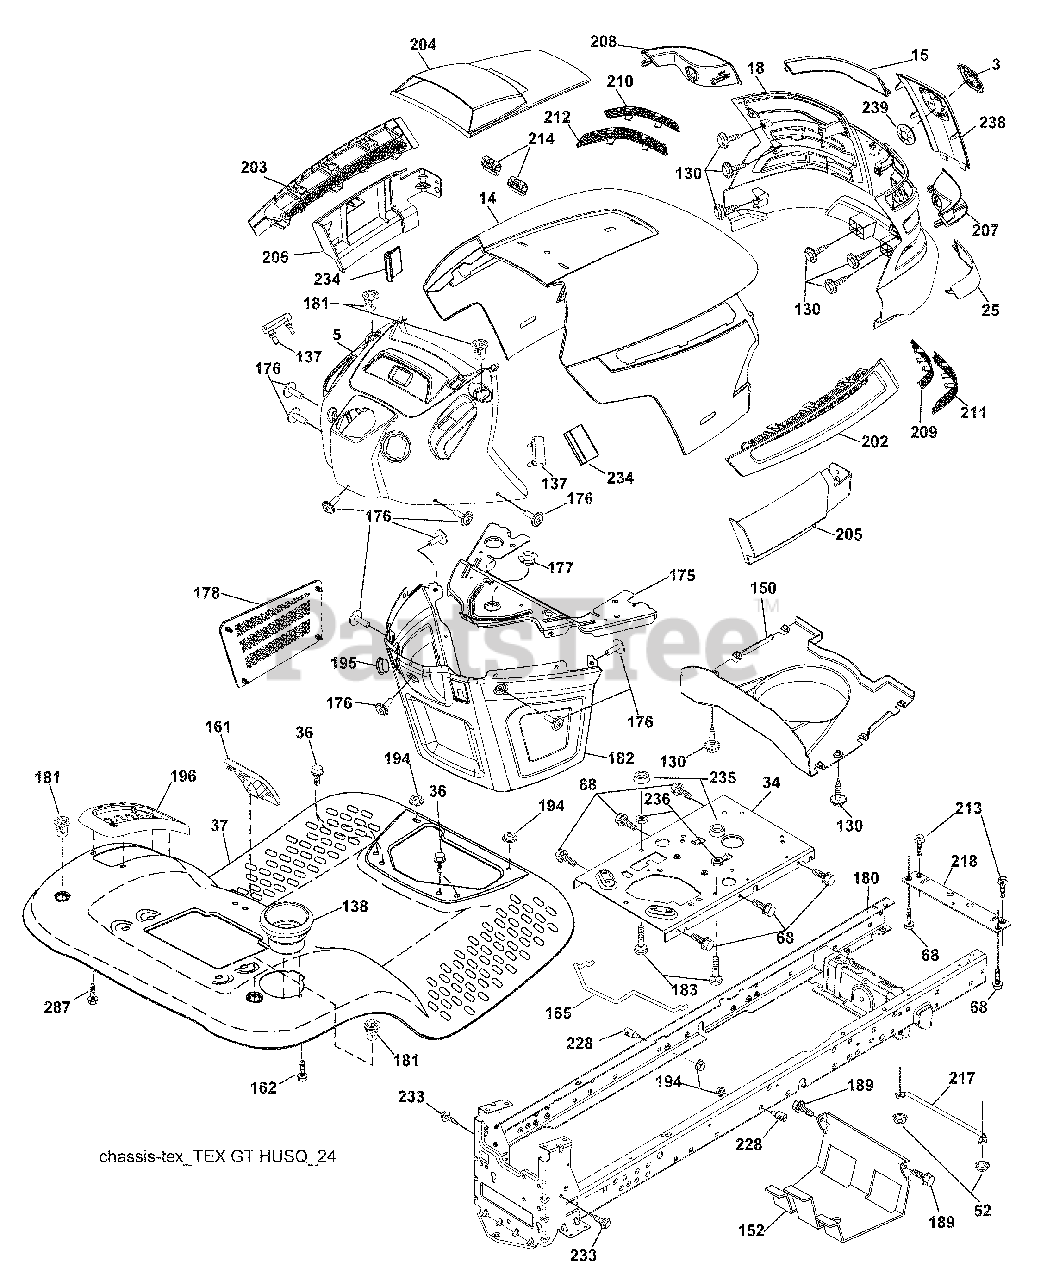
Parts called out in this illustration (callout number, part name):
3	Logo
14	Hood
18	Grille Asm.
34	Plate Engine
36	Screw 5/16-18 x 3/4
52	Nut Lock 5/16-18
68	Screw 5/16-18 x 1/2
130	Screw #10 x 0.750 BOS Thread
137	Bumper Dash
138	Cupholder
152	Shield Browning
161	Window Fuel
165	Support Tank Rear
175	Crossmember
176	Screw 10-24 x 5/8
177	Bushing Steering
178	Cargo Net Asm.
180	Chassis
181	Bushing Mtg. Fender Crgo
182	Dash Lower
183	Bolt Fin Hex 5/16-18 unc x 1-1/4
189	Screw 5/16-18 x 3/4
194	Nut Lock Hex Flange 5/16-18
195	Plug Hole Dash Lower
196	Console Asm. Deck Lift
202	Vent Side Hood RH
203	Vent Side Hood LH
204	Vent Top Hood
205	Skirt Hood Side RH
206	Skirt Hood Side LH
209	Insert Hex Top RH
210	Insert Hex Top LH
211	Insert Hex Bottom RH
212	Insert Hex Bottom LH
213	Bolt 5/16-18 unc x 3/4
214	Clip Retainer Tinner
218	X-Piece Hood Stop
228	Stud Fastner
233	Bolt Shoulder
234	Bumper Hood
235	Spacer Fender
236	Nut Lock 5/16-18 unc
287	Screw Hex Washead 1/4-20 x 3/8
